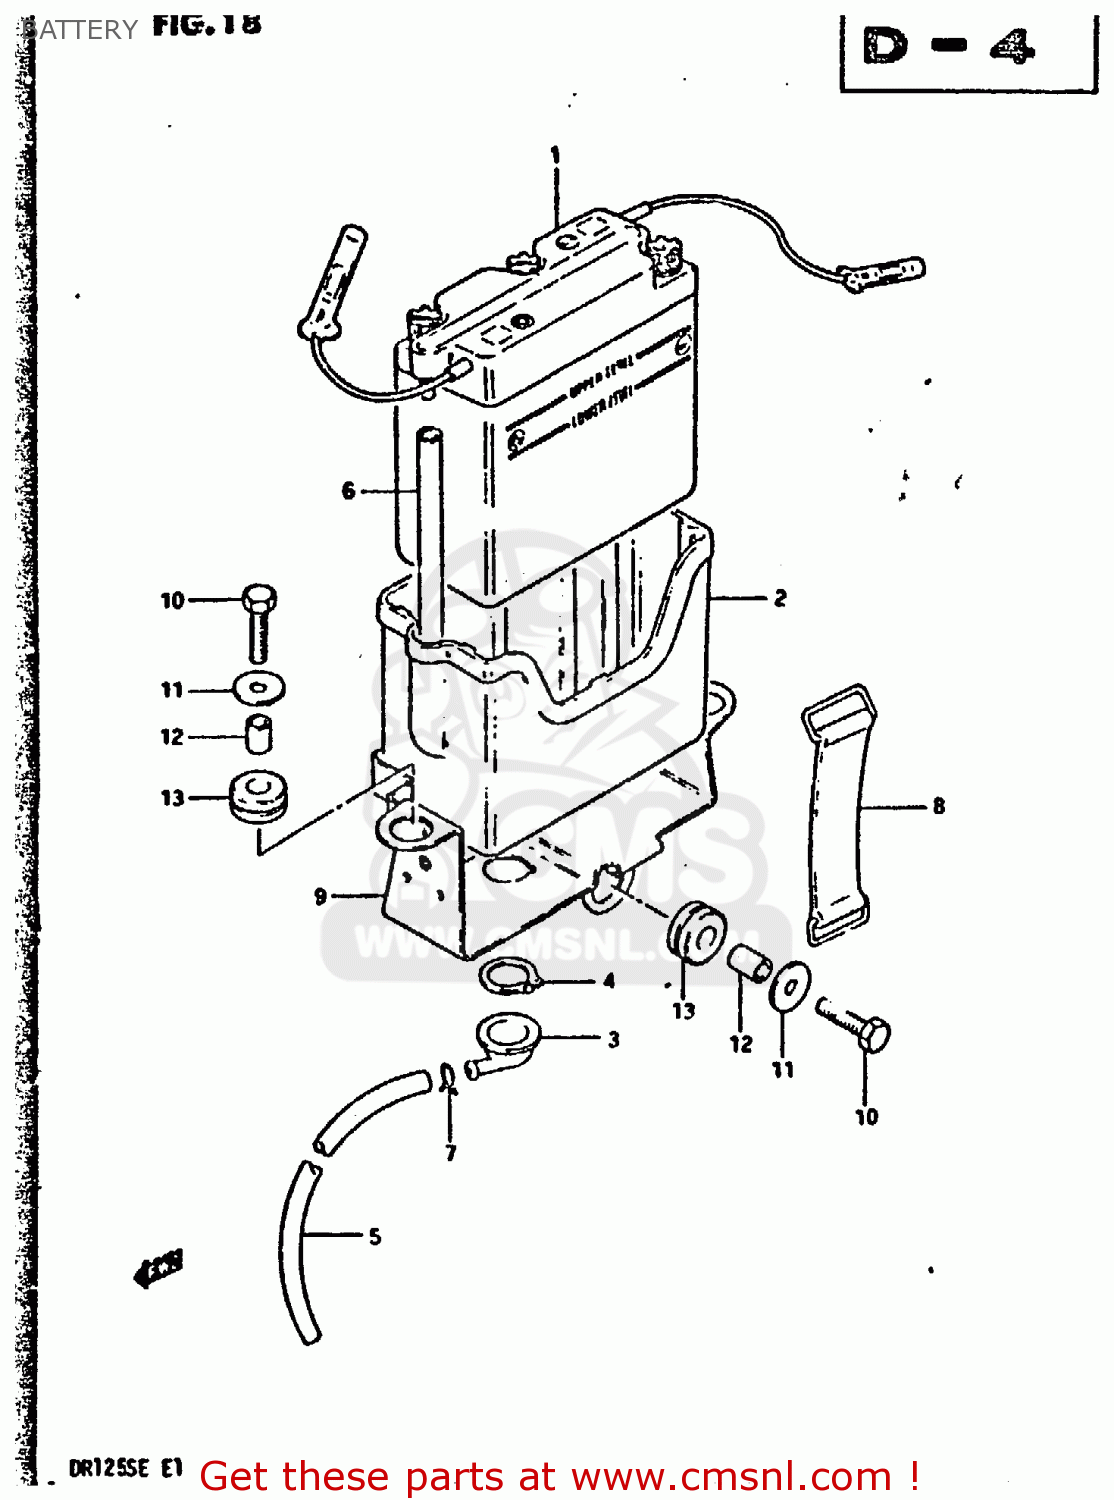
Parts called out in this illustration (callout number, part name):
1	BATTERY (6V, 4AH)
2	CASE,BATTERY
3	FUNNEL,BATTERY EXHAUST
4	CIRCLIP
5	HOSE,BATTERY EXHAUST
6	HOSE, EXHAUST (L:45)
7	CLIP
8	BAND
9	HOLDER,BATTERY
10	BOLT, UPPER
11	WASHER (6.5X20X1.2)
12	SPACER(6.1X9X7.5)
13	CUSHION
